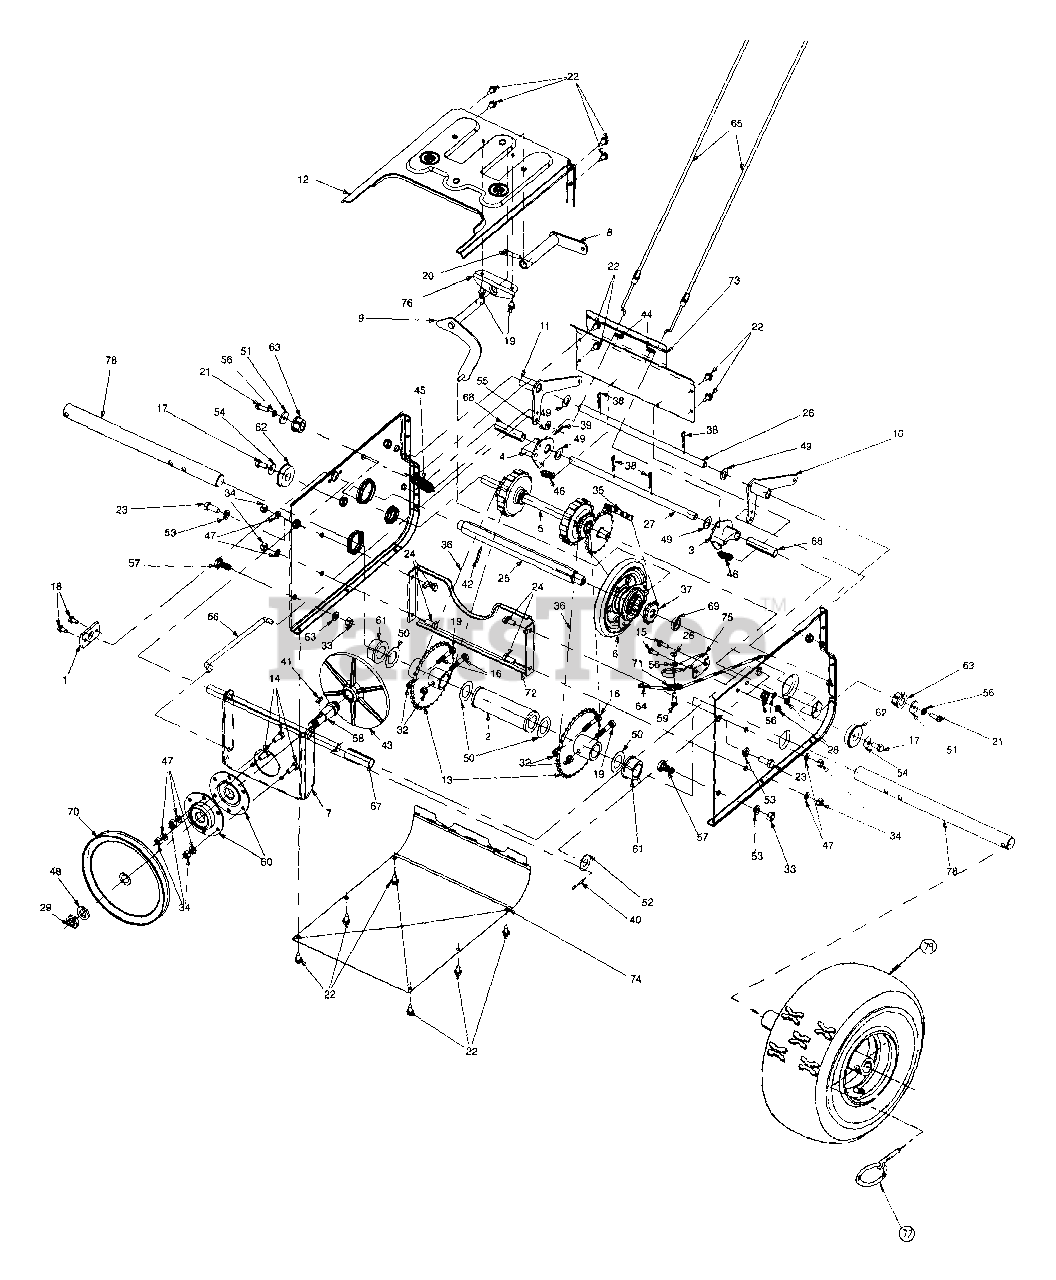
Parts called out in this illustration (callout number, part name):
1	Pivot Axle Brkt..63 Hole - Zinc
2	Bush Asm slev 900 Strbl
3	Dogg Asm Dr Lh 900 Strbl
4	Dogg Asm;dr Rh 900 Strbl
5	Shf Asm Dr 900 Strbl
6	Whl Asm Brg 6.0 Od Friction
10	Brkt Asm Actr Auger
14	Hex Scr 5/16-18 X .75
15	Hhcs 1/4-28 .625 Gr5 std
16	Hex Scr 5/16-18 X 1.75
17	Hhcs 5/16-18 .625 Gr5 Lock
18	Scr tt 1/4-20 .5 Hxindwsh
19	Hex Scr 5/16-18 2.00 Lg
20	Scr Hexwash 1/4-20 X 1.25
21	Scr Tt Cl 1/4-20 .75 Hxindwsh
22	Scr Ab 1/4-14 .625 Hxindwsh
23	Hhcs 3/8-16 .880 Gr5 Std
24	Scr Cap 5/16-18 X .75 Gr 5
25	Shf Dr .875 Hex 900
26	Shf Sctr
27	Shf Actr Dr
28	Hex Nut 1/4-28
29	Hex Ins Jam L-nut 5/8-18
32	Hex Ins L-nut 5/16-18
33	Hex Nut 3/8-16
34	Nut Hex 5/16-18 Gd 5
35	#41 Chain 1/2 Pitch X 36 L
36	#420 Chain 1/2 Pitch X 40 L
37	Spkt 10t #41 X .500
38	Internal Cot-pin 1/2 Dia
39	Intern Cot-pin 5/16 Dia
40	Cotter Pin 1/8 Dia X 1
41	#61 Hi-pro-key 3/16 X 5/8
42	Spring Pin Roll 5/32
43	Aluminum Drive Plate
44	Plug 5/8 Snap-in
45	Idler Extension Spring
46	Extension Spring
47	Lock Washer 5/16
48	Lock Washer 5/8
49	Wash Fl .531 Id X .930 Od X .05
50	Wash Fl 1.03 Id X 1.62 Od
51	Wash Flt 1/4 Id X .930 Od X .12
52	Wash Flt .640 Id X 1.24 Od X .06
53	Lock Washer 3/8 Heavy
54	Bell Wash .345 Id X .88 Od
55	Fl-wash Sae .34 X .68 .062
56	Lock Washer 1/4
57	Shld Scr .498 Dia X .340
58	Drive Plate Spindle
59	Scr Shldr .340 D. 1/4 Ab
60	Asm Brg Hsg
61	Flange Brg Pm W/fits 1.0
62	Ball Bearing W/snap Ring
63	Brg Hex Flange X .564 Id
64	Cb Idlr Auger
65	Cbl Strg 900 Strbl
66	Rod Clu Dr
67	Spcr Spit .64 X .77 X 2.1
68	Split Spacer 1/2 X 5/8 X 2.44
69	Spcr .675 Id X 1.00 Od X .23
70	1/2 V-pulley .62 Id X 7.5
71	Cable Guide Roller
77	Klik Pin Assy Danuse
78	Axle 1.0 Od X 14.1 Lg
